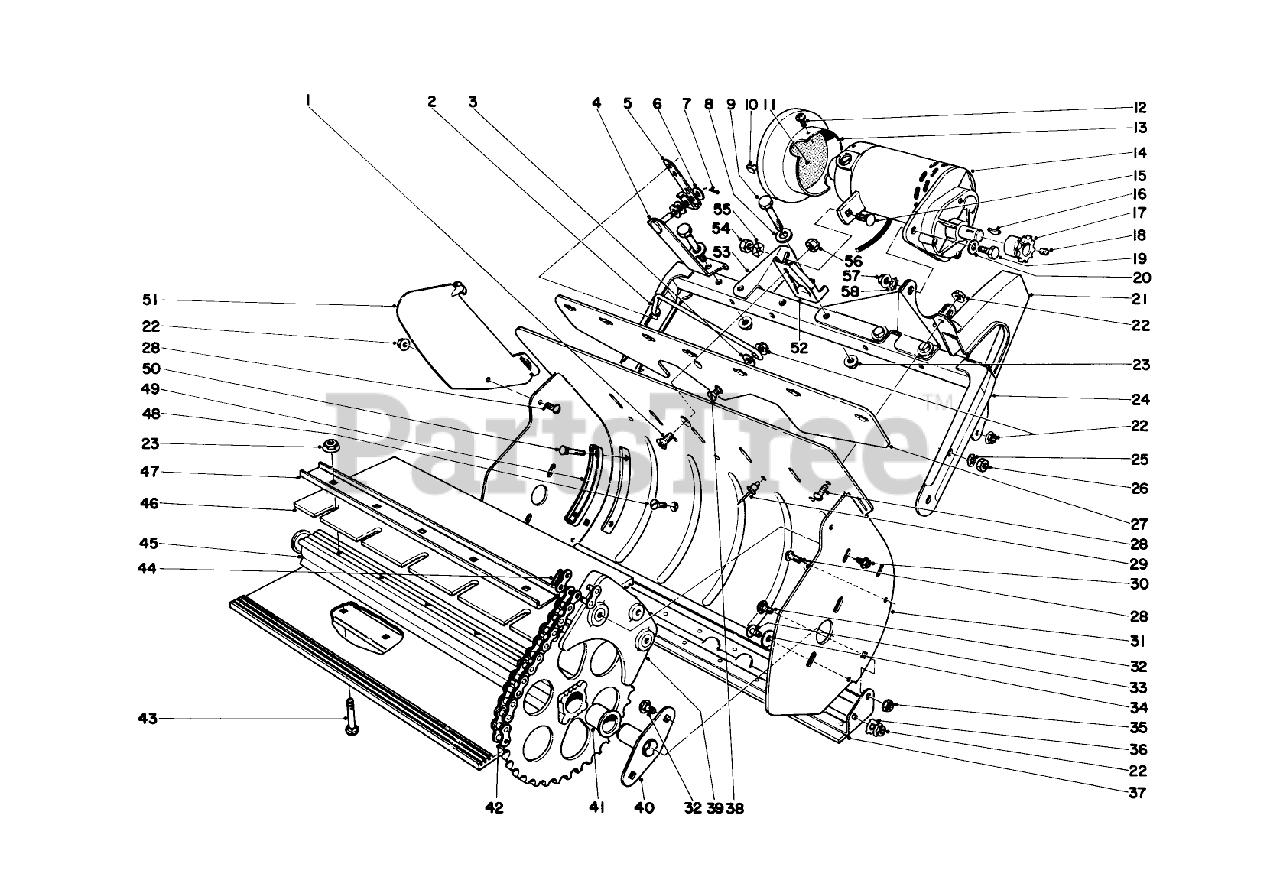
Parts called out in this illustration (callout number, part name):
1	SCREW-FH, S
2	Linkage Vane Adj.
3	WASHER-FLAT
4	Vane Adj. Bracket
6	WASHER-FLAT
7	PIN-COTTER
8	WASHER-FLAT
9	SCREW-HH
10	Clip Tinnerman
11	Housing
13	Filter Assy.
14	Motor
15	BOLT-CARR
18	SCREW-SET, HSH
19	SCREW-HH
20	WASHER-PLAIN
22	NUT-LOCK, FLANGE
24	Frame Assembly
28	SCREW-PTH
31	Housing
33	SCREW-HEAD, PAN
35	NUT-KEPS
36	Washer
38	10-24X1-1/8 FLT HD MS
42	CHAIN
44	LINK-CONNECTING, NO. 35
47	Reinforcing Strap
50	SCREW-CARR
52	Stiffener
53	Bracket Rear
54	NUT-HEX
55	WASHER-LOCK
56	NUT-LOCK, NI
57	NUT-HHF
